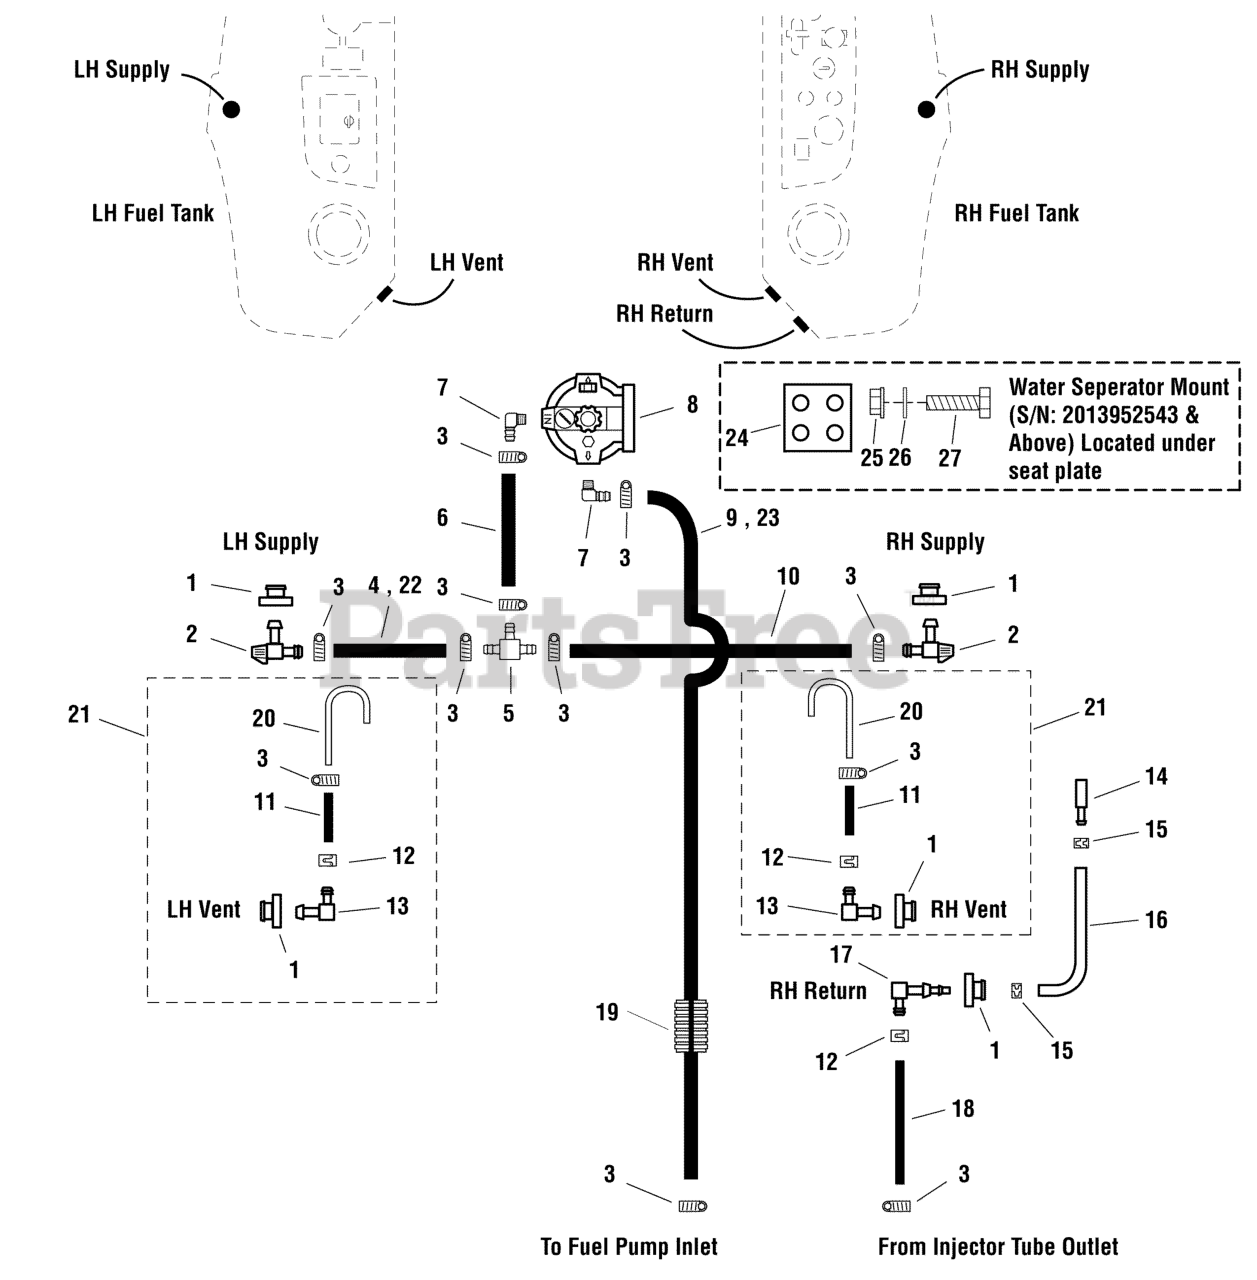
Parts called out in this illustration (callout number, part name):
1	BUSHING-FUEL TANK RED RUBBER
2	VALVE, Fuel Shut Off
3	CLAMP, #4 Hose
4	HOSE, 3/8" FUEL, 26.50"
5	FITTING, TEE, 3/8" Hose
6	HOSE, 3/8" FUEL, 3.50"
7	FITTING, 1/4" NPT, 90 Deg.
8	FILTER/WATER SEPARATOR ASSEMBLY, Complete
8	FUEL FILTER
8	O-RING SEAL
9	HOSE, 3/8" FUEL, 54.00"
10	HOSE, 3/8" FUEL, 35.00
11	HOSE, 1/4" FUEL, 8.00"
12	CLAMP, Hose
13	ELBOW FITTING
16	HOSE ASSEMBLY
18	HOSE, 1/4" FUEL, 33.50"
19	LOOM, 5/8" I.D., 25
20	VENT TUBE, DIESEL
21	KIT, FUEL TANK VENT LINE
22	HOSE, 3/8" FUEL, 4.5"
23	HOSE, 3/8" FUEL, 56"
24	MOUNT, WATER SEPERATOR - RED
25	NUT, 3/8-16 HEX NYLOCK FLANGE
26	WASHER, 3/8 SAE
27	BOLT, 3/8-16 X 3/4" GD5 CZ
